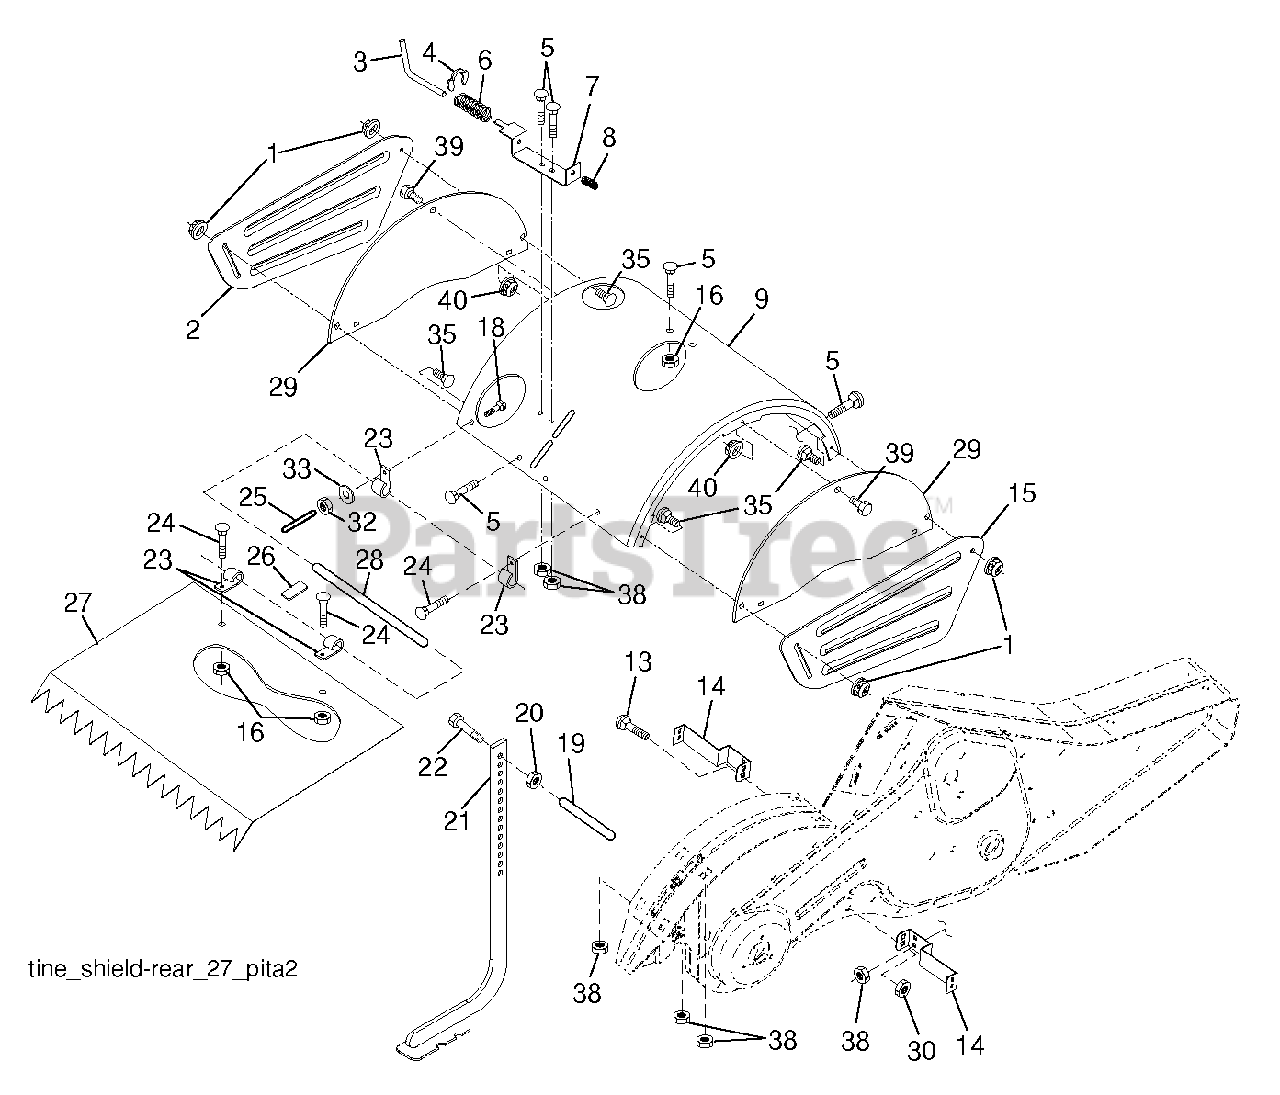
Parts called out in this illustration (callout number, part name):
1	NUT.FLANGE.5/16
3	STAKE PIN TI
4	RING, KLIP
5	BOLT, RDHD SQNK 5/16-18 X 3/4
6	SPRING TI
8	SPRING CRT
13	BOLT.CARRIAGE.5/16-18
14	BRACKET.TINE.SHIELD.TILLER.BLA
15	SHIELD.SIDE.OUTER.LH.BLACK.GLO
16	NUT T
19	GRIP CRT
20	NUT.HEX.3/8-16UNC
22	BOLT.375-16
23	HINGE CRT
25	VINYL CAP
26	PAD IDLER TI
28	PIN.HINGE.TILLER
29	SHIELD.SIDE.PNT.428
30	LOCKNUT-FLANGE 5/16-18
32	NUT
33	LOCKWASHER
35	BOLT.CARRIAGE.5/16-18X
39	BOLT.HEX.HD.WASHER.5/16-18X.75
40	NUT.SPEED.5/16-18
